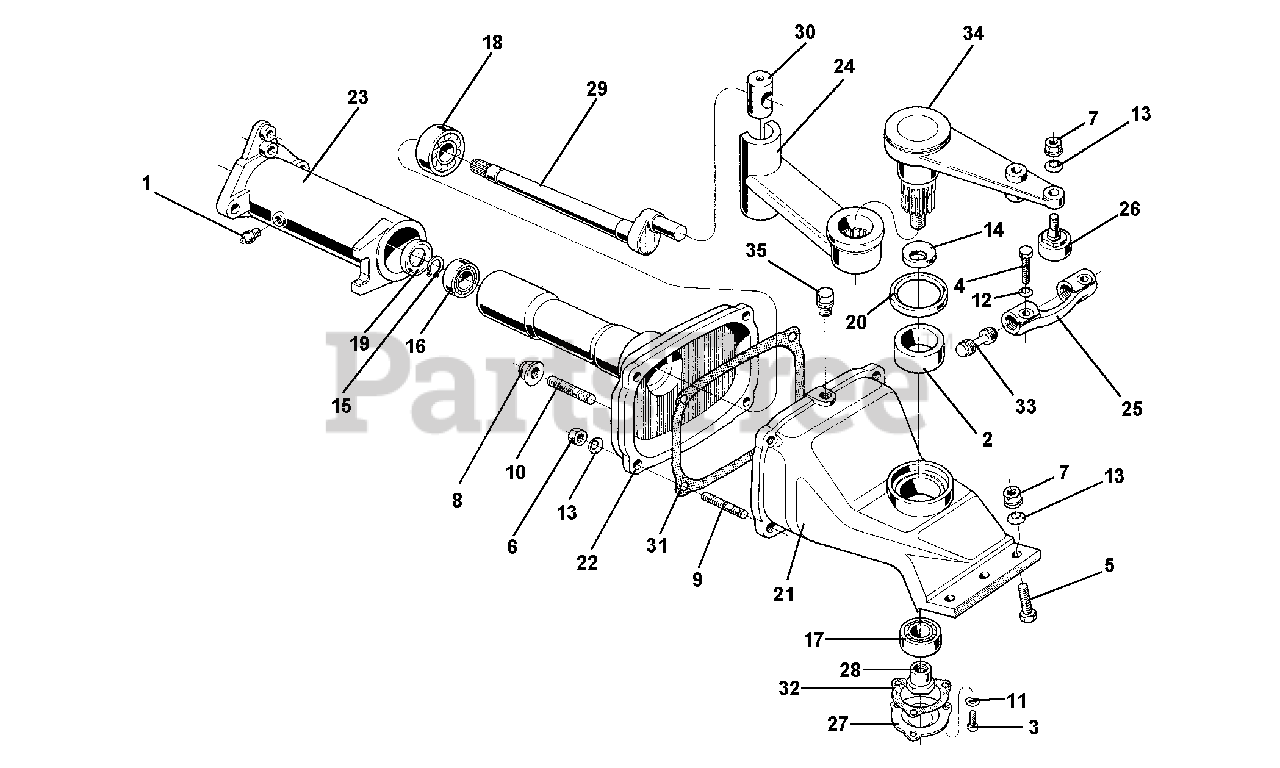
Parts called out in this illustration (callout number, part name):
1	LUBRICATOR M10
3	SCREW M6 X 12
4	SCREW M8 X 35
7	SELF LOCKING NUT
10	STUD M12 X 50 X 30 X 15 8G
11	SUPER WASHER 6 DIN 6796
12	SUPER WASHER 8 DIN 6796
13	SUPER WASHER 10 DIN 6796
14	SUPER WASHER 18 DIN 6796
15	CIRCLIP EXTERN. D 20
16	BEARING 20 X 42 X 12 6004
17	BEARING 25 X 52 X 16 6205
18	BEARING 25 X 62 X 17 6305
19	SEAL, OIL 20 X 42 X 7 STANDARD
21	BLADE CONTROL BOX
22	BAR CONTROL SUPPORT
23	BAR CONTROL BUSH
24	CONTROL CRANK
25	STEEL BLADE COUPLING
26	BLADE CONTROL PIN
27	LOWER COVER
28	SPECIAL NUT
33	BLADE COUPLING SCREW
34	CONNECTING ROD
35	BREATHER CAP 1/4 GAS
